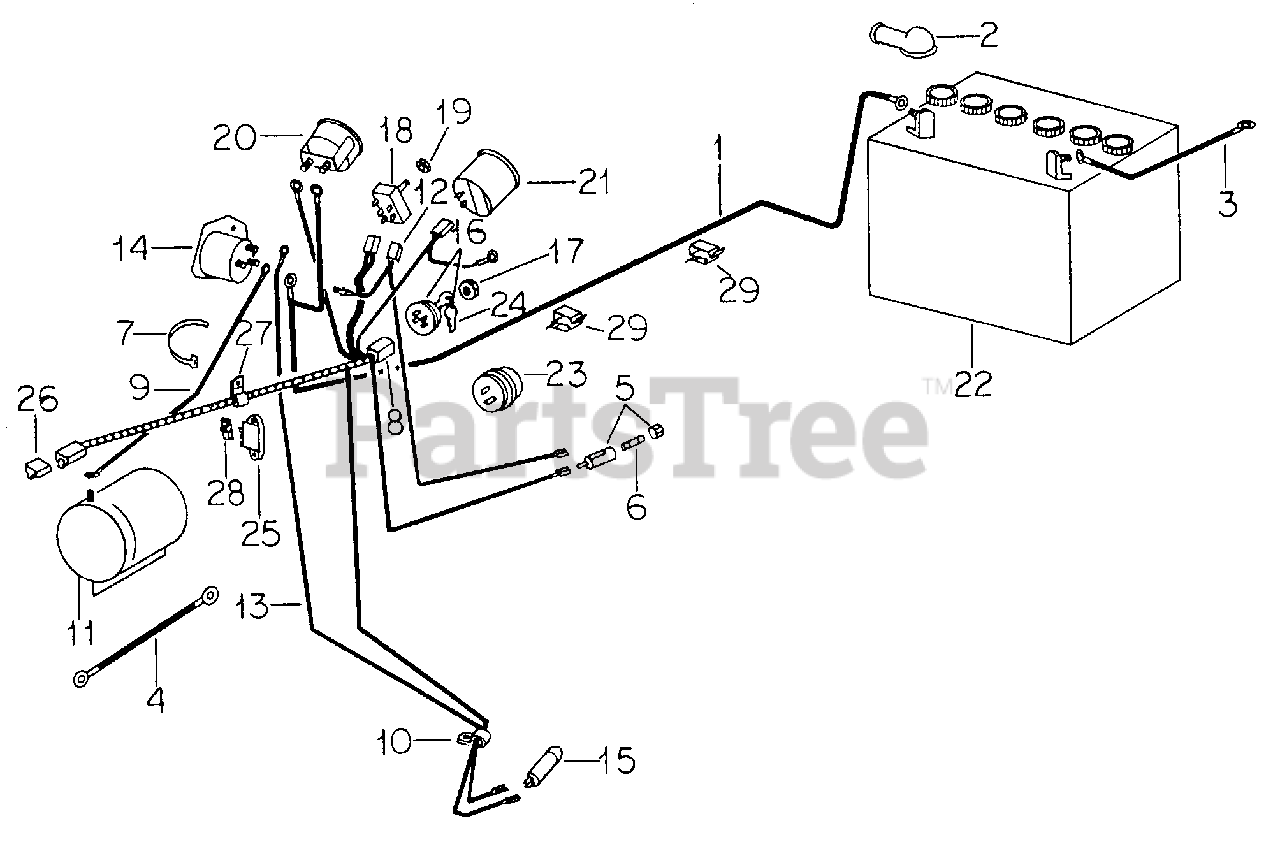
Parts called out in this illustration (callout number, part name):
1	Cable, Battery (Positive)
2	Cover, Battery Terminal
3	Cable, Battery Negative to Ground
4	Cable, Engine to Ground
5	Holder, Fuse
6	Fuse, 10 Amp
7	Strap, Cable Lock
8	Cable, Key Switch
9	Cable, Magnetic Switch to Cranking Motor
10	Clip, Cable (Steering)
11	Starter Motor Assy
12	Cable Assy, Clutch Switch
13	Cable, Magnetic Switch to Neutral Starting Switch
14	Switch, Magnetic
15	Switch, Neutral Start
16	Switch, Battery Ignition Key Start
17	Nut, Battery Ignition Switch
18	Switch, PTO
19	Nut, Switch
20	Indicator, Charge
21	Timer, Maintenance Minder
22	Battery, IH Low-Maintenance, 12 Volt
23	Not used in this application
24	Key, Battery Ignition Switch
27	Clip, High Tension
28	Connector
29	Clip, Battery Cable
